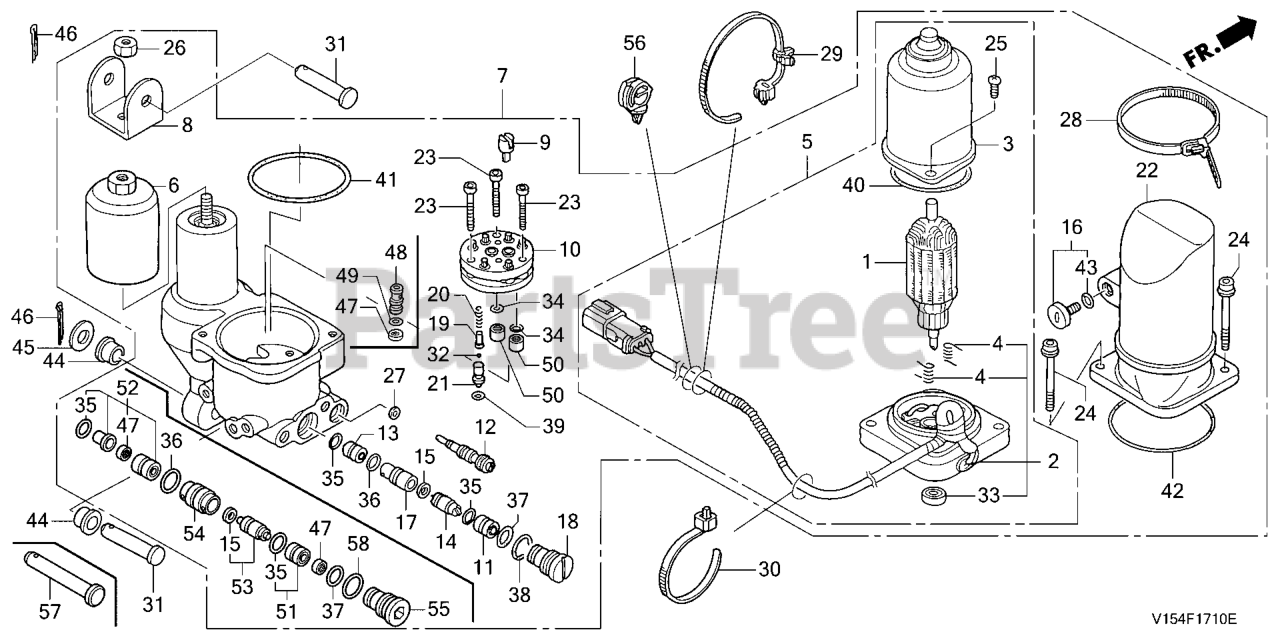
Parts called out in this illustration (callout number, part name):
2	BRACKET ASSY.
4	SPRING, MOTOR
5	MOTOR ASSY., POWER HEIGHT
6	COVER, DUST END
7	HEIGHT ASSY., POWER
8	JOINT, METAL
9	JOINT, DRIVE
12	VALVE, MANUAL
15	RING, BACK-UP
16	BOLT, PLUG
19	GUIDE, SPRING
20	SPRING, VALVE
23	BOLT, SOCKET
24	BOLT, SOCKET
25	SCREW, PAN (5X0.8)
28	BAND, WIRE HARNESS
29	BAND, WIRE HARNESS
31	PIN (12X46)
32	BALL, STEEL
34	O-RING (1.5X8.5)
35	O-RING (1.5X10.7)
36	O-RING (1.5X13.5)
37	O-RING (1.5X15.5)
41	O-RING (2.0X62.5)
42	O-RING (2.4X66.6)
43	O-RING (1.9X9.8)
44	BUSH, CYLINDER (UPPER)
45	WASHER, PLAIN (12MM)
46	PIN, SPLIT (3.0X25)
46	PIN, COTTER (3.0X45)
48	SEAT, VALVE
49	O-RING (1.5X5.5)
53	SPOOL, VALVE
56	CLIP, WIRE HARNESS (25MM)
57	PIN (12X55.5)
58	O-RING (1.8X18.8)
